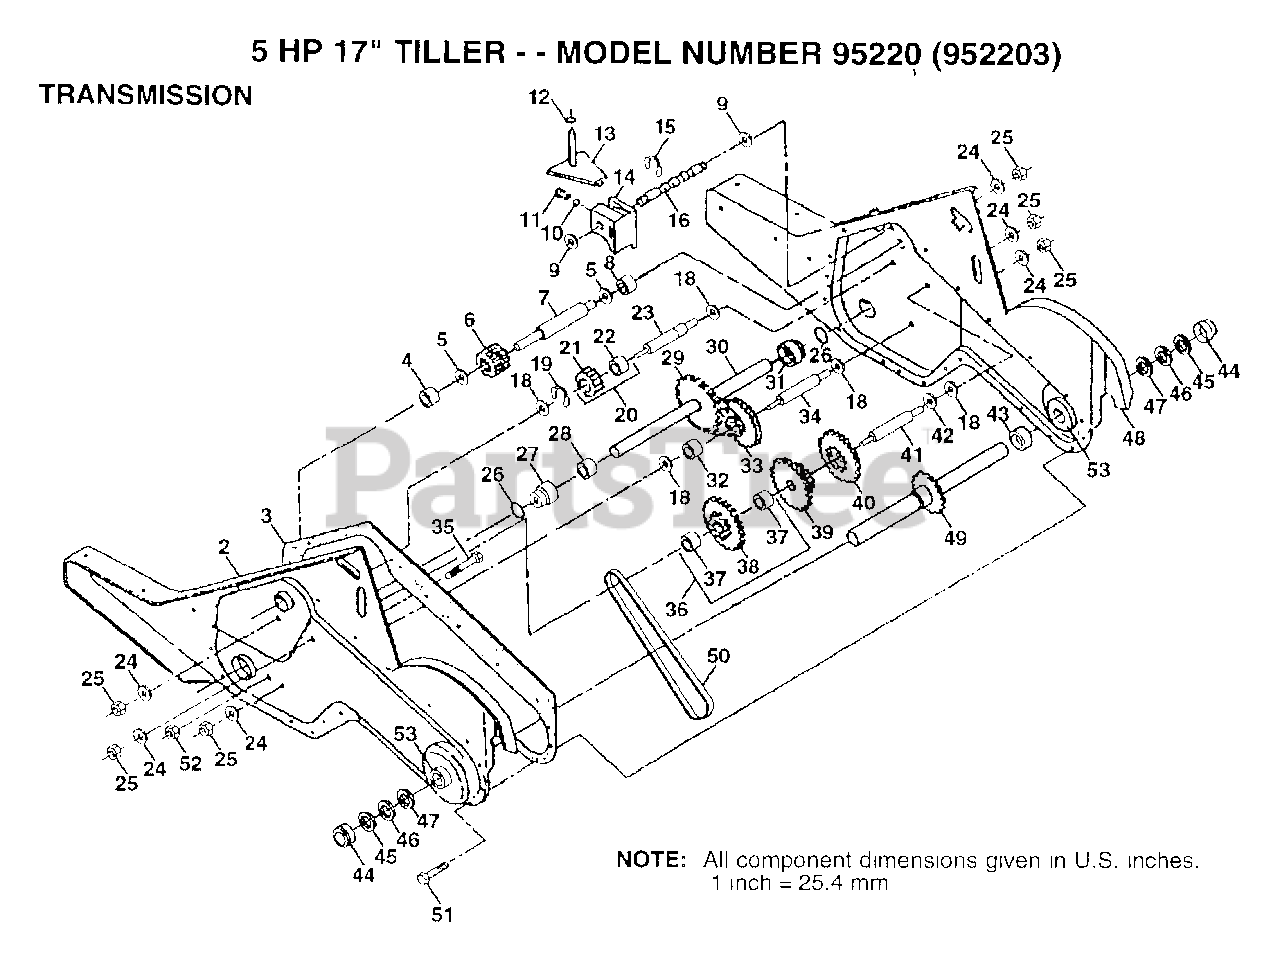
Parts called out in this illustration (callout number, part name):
2	GEARCASE, L.H.
3	GASKET TI
4	NEEDLE BRNG LT
5	"T, BEARING"
6	GEAR PINION INPUT
7	SHAFT-INPUT CRT
8	"TI, BEARING"
9	WASHER SEAL CRT
11	SPRING-SHIFT CRT
12	O-RING TI
13	BRACKET ASM SHIFT
14	SHIFT FORK TI
15	KLIP RING
16	SHAFT.SHIFT.4.250
18	WASHER
19	KLIP RING
20	GEAR ASSY CRT
21	GEAR-REV IDLR CRT
22	NEEDLE BEARING TI
23	SHAFT CRT
24	LOCKWASHER
25	NUT.ASF.HEX.7/16
26	O RING CRT
27	"CRT, BEARING"
28	BUSHING TI
29	CHAIN CRT
32	SPACER TI
33	SPRCKT 8 GEAR CRT
34	SHFT 2ND RED. CRT
35	SCRW WHIZ LOK CRT
36	SPROCKET ASM.
37	BEARING
39	GEAR TI
40	GEAR TI
41	REDUCTION SHFT TI
42	BRNG RACE
43	SPACER TI
44	CUP.FORMED.
45	RING SPIRAL CRT
46	SEAL RING RUBBER
47	OIL SEAL STD
49	TINE SHAFT
50	CHAIN.50 LINK TI
51	SCREW CRT
52	NUT.HEX.5/16-18
